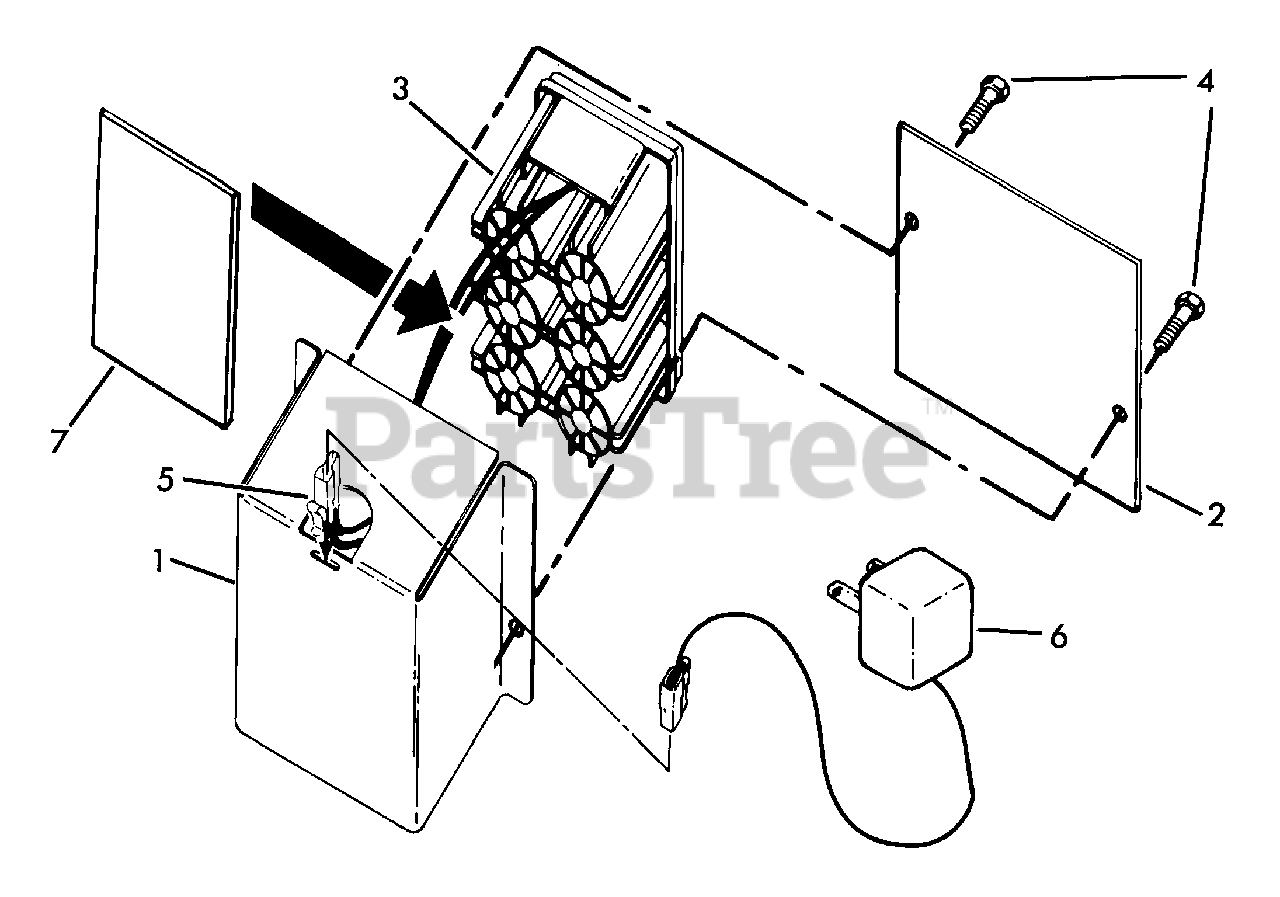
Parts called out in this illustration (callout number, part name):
1	Battery Bracket
2	Battery Cover
3	Battery Kit
4	Hex Washer Head Screw #10-24 x 1/2
5	Connector Mounting Clip
6	Battery Charger
7	Battery Pad
